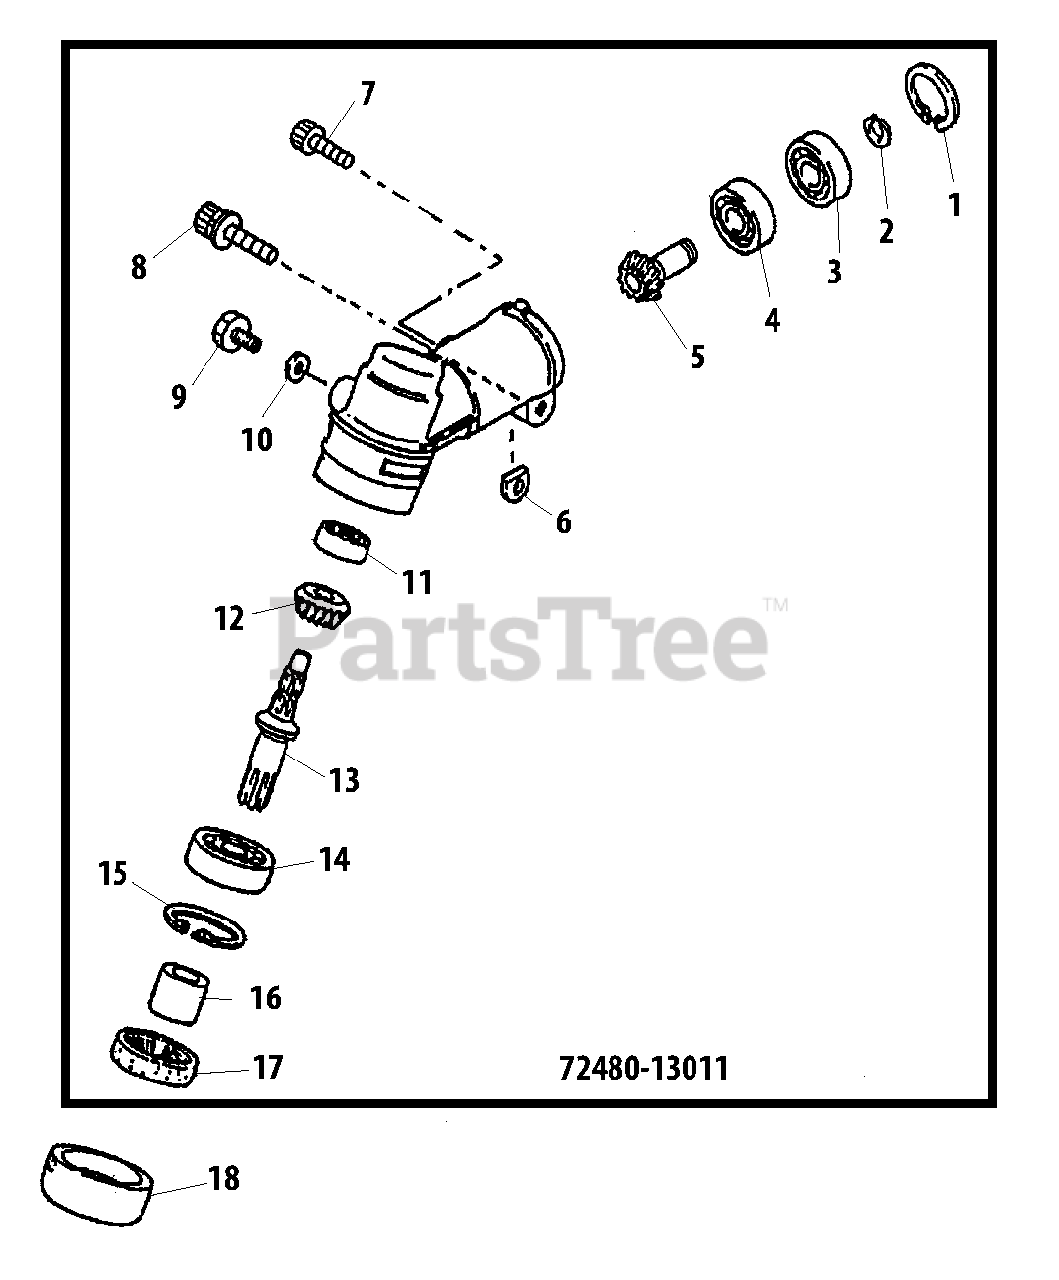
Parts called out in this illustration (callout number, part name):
1	RING, RETAINING - 22
2	RING, RETAINING
3	BEARING, BALL - 608ZZ
4	BEARING, BALL - 608
5	GEAR - SHAFT
6	SHIM
7	SCREW - 5X12
8	SCREW - 5X25
9	BOLT - 6X10
10	WASHER
11	BEARING, BALL - 626
12	GEAR - BEVEL
13	GEAR - SHAFT
14	BEARING, BALL - 6000
15	RING, RETAINING - 26
16	COLLAR
17	SEAL, OIL
18	HOLDER
72480-13011	GEAR CASE ASSY
